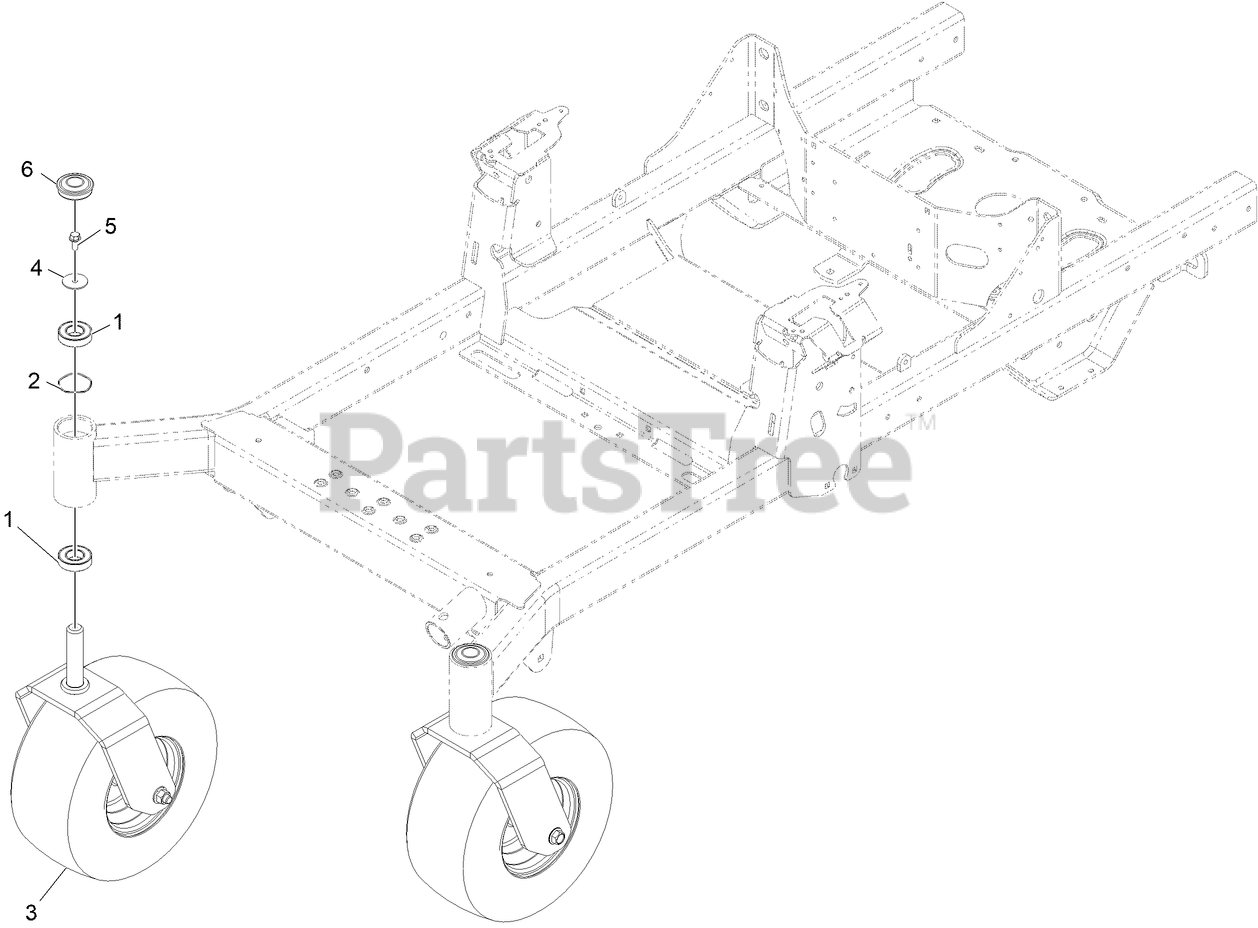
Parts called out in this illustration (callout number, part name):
1	BEARING-BALL
3	ASM-Front Caster W/Fork
4	WASHER-FLAT
5	SCREW-HHF
6	CAP, GREASE
